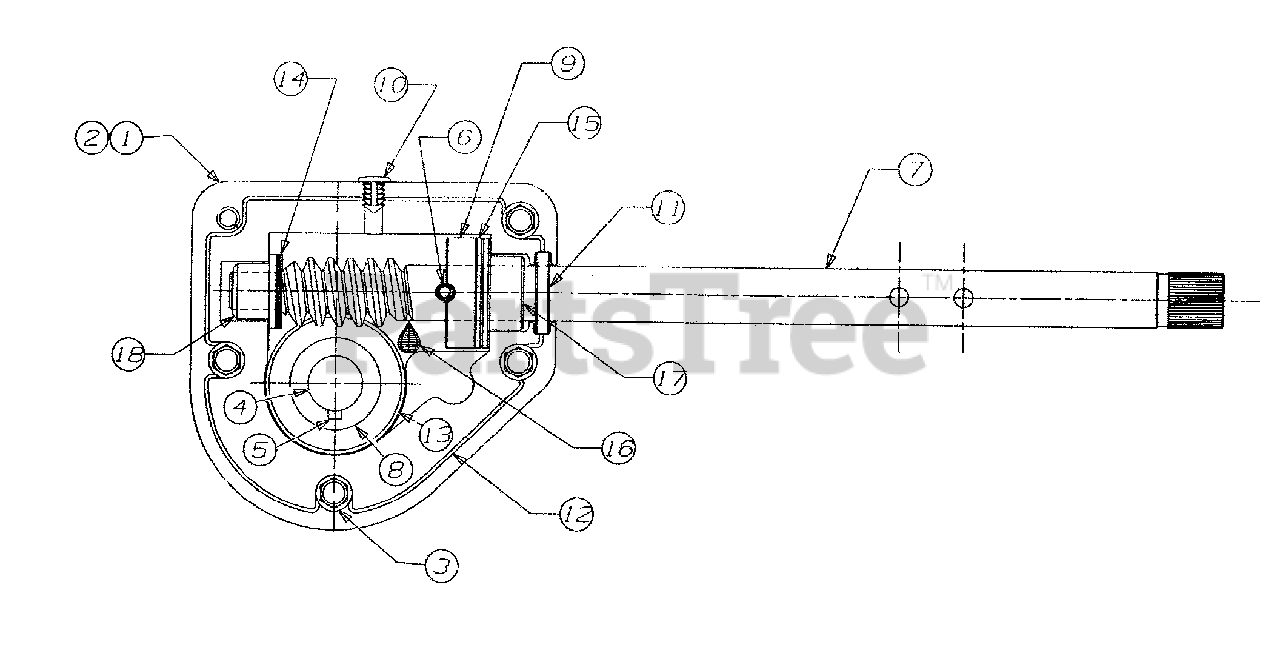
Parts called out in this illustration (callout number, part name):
1	Housing - R.H.
2	Housing - L.H.
3	Screw
4	Axle, Spiral 30"
5	Key, Hi-Pro
6	Pin, Spiral
7	Worm, Shaft
8	Gear, Worm
9	Collar, Thrust
11	Seal, Oil
12	Loctite 5699
13	Washer - Flat
14	Washer - Flat
15	Washer - Flat
16	Grease
17	Bearing Flange
18	Bearing Flange
